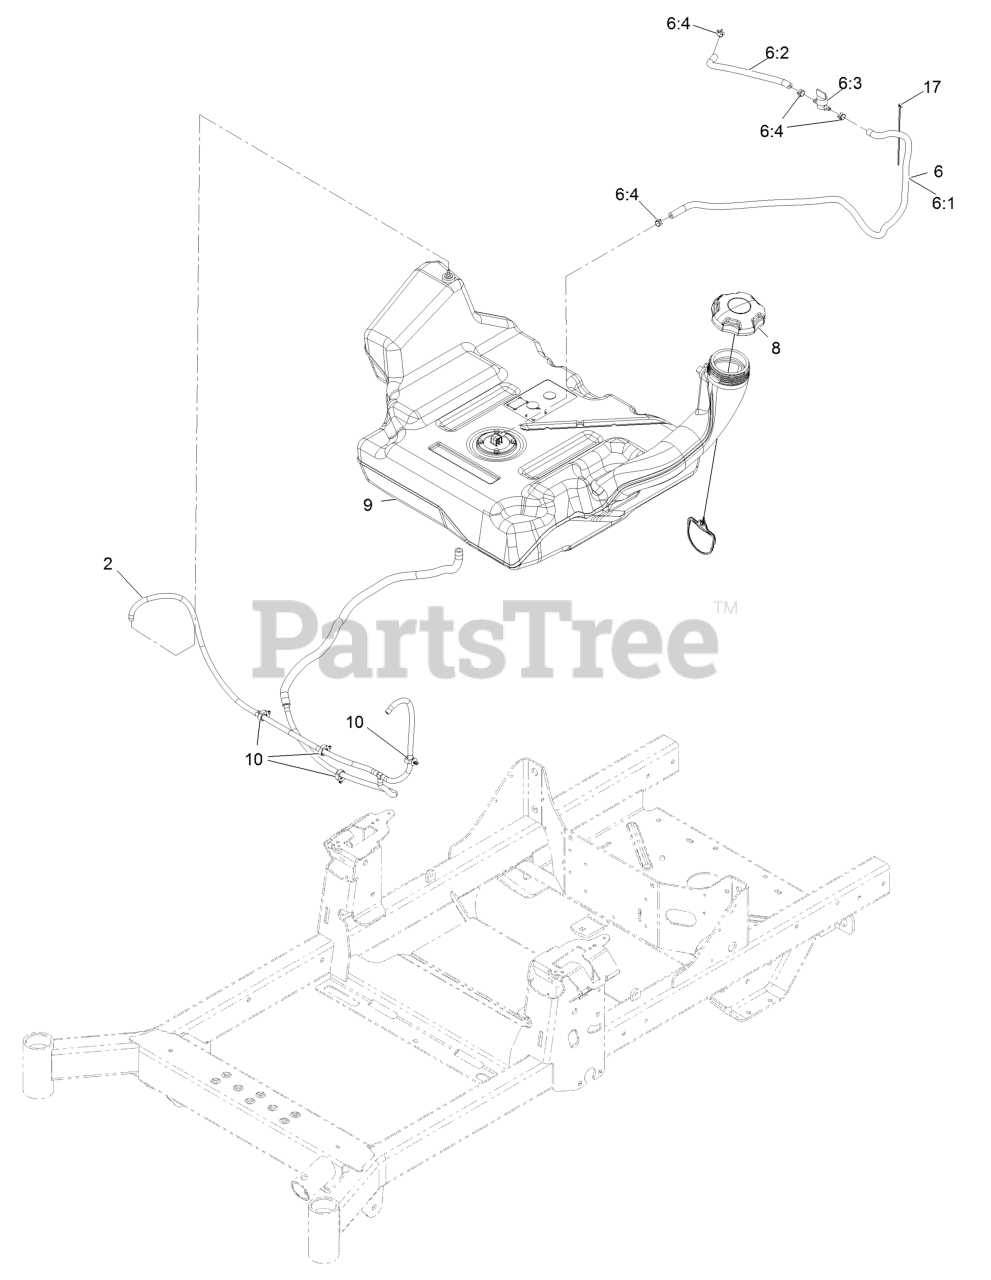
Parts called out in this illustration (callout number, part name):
2	HOSE-VENT
6	FUEL HOSE ASM
6:1	HOSE-FUEL
6:2	HOSE-FUEL
6:3	VALVE-FUEL
6:4	CLAMP-HOSE
9	TANK-FUEL
17	TIE-CABLE
